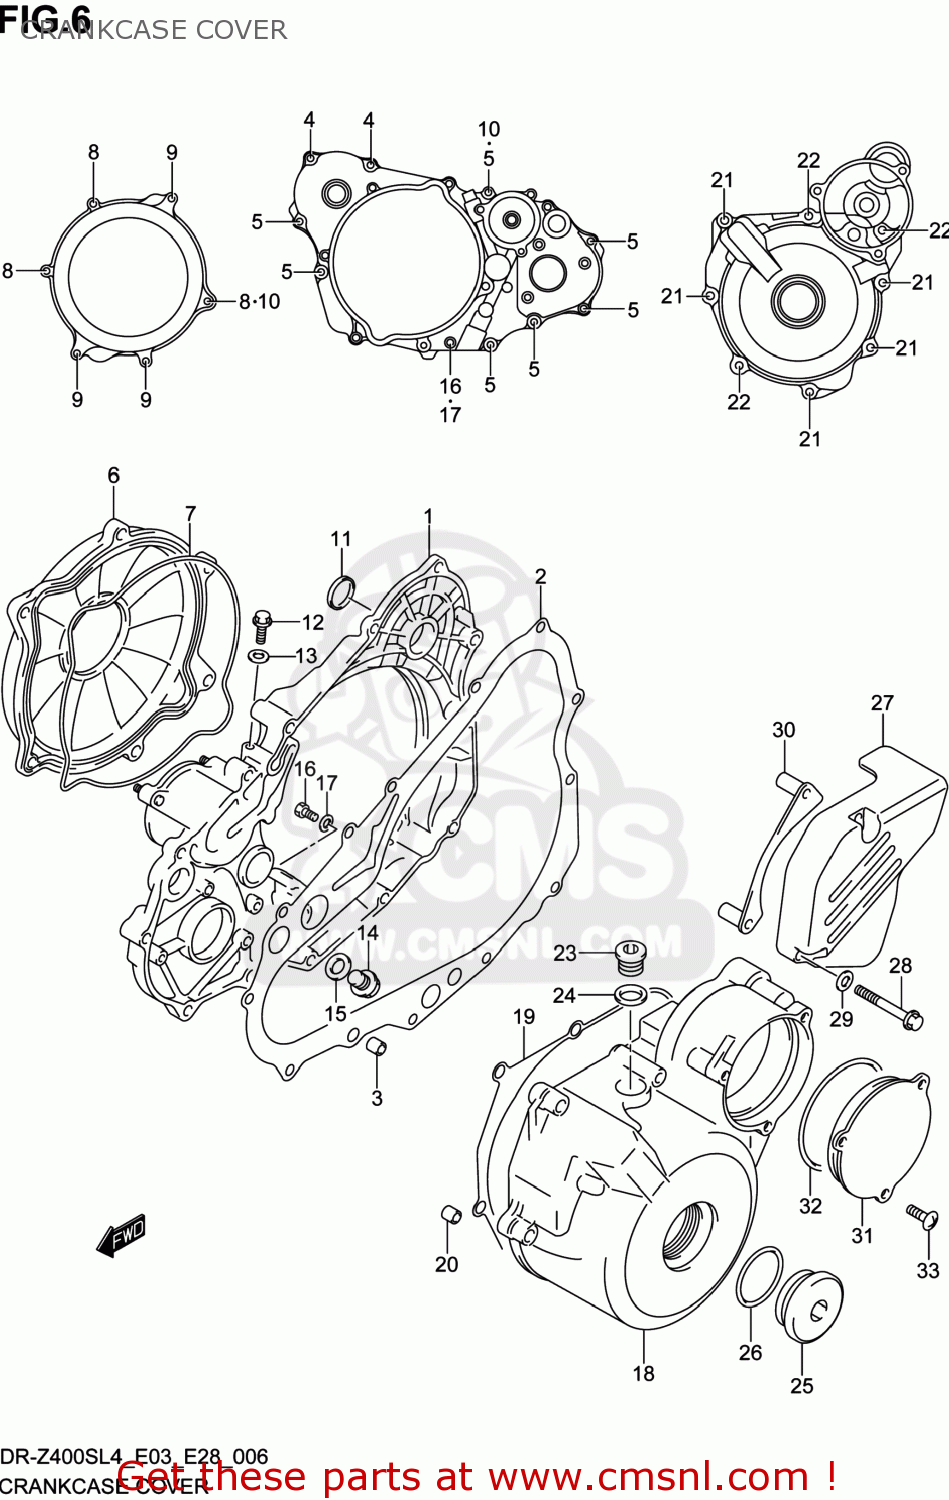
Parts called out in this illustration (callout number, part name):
1	COVER,CLUTCH INNER
2	GASKET,CLUTCH COVER (NAS)
3	PIN
4	BOLT
5	BOLT
6	COVER,CLUTCH OUTER
7	O RING,CLUTCH COVER OUTER
8	BOLT
9	BOLT
10	GASKET(5.8X13X1.2) (NAS)
11	PLUG,CLUTCH COVER KICK
12	BOLT
13	GASKET(5.8X13X1.2) (NAS)
14	PLUG(12X10)
15	GASKET(12.1X16.2X3.7) (NAS)
16	BOLT
17	GASKET(6.2X11X1).2 (NAS)
18	COVER,MAGNETO
19	GASKET,MAGNETO COVER (NAS)
20	PIN
21	BOLT
22	BOLT
23	PLUG,14X12
24	GASKET(13.8X18.8X4.8) (NAS)
25	PLUG(SILVER)
26	O RING(D:3.1,ID:32.7)
27	COVER,ENGINE SPROCKET
28	BOLT
29	WASHER(6.5X14X2)
30	PLATE,FR CHAIN GUIDE
31	COVER,STARTER IDLE GEAR
32	O RING(D:2.6,ID:67.1)
33	SCREW
